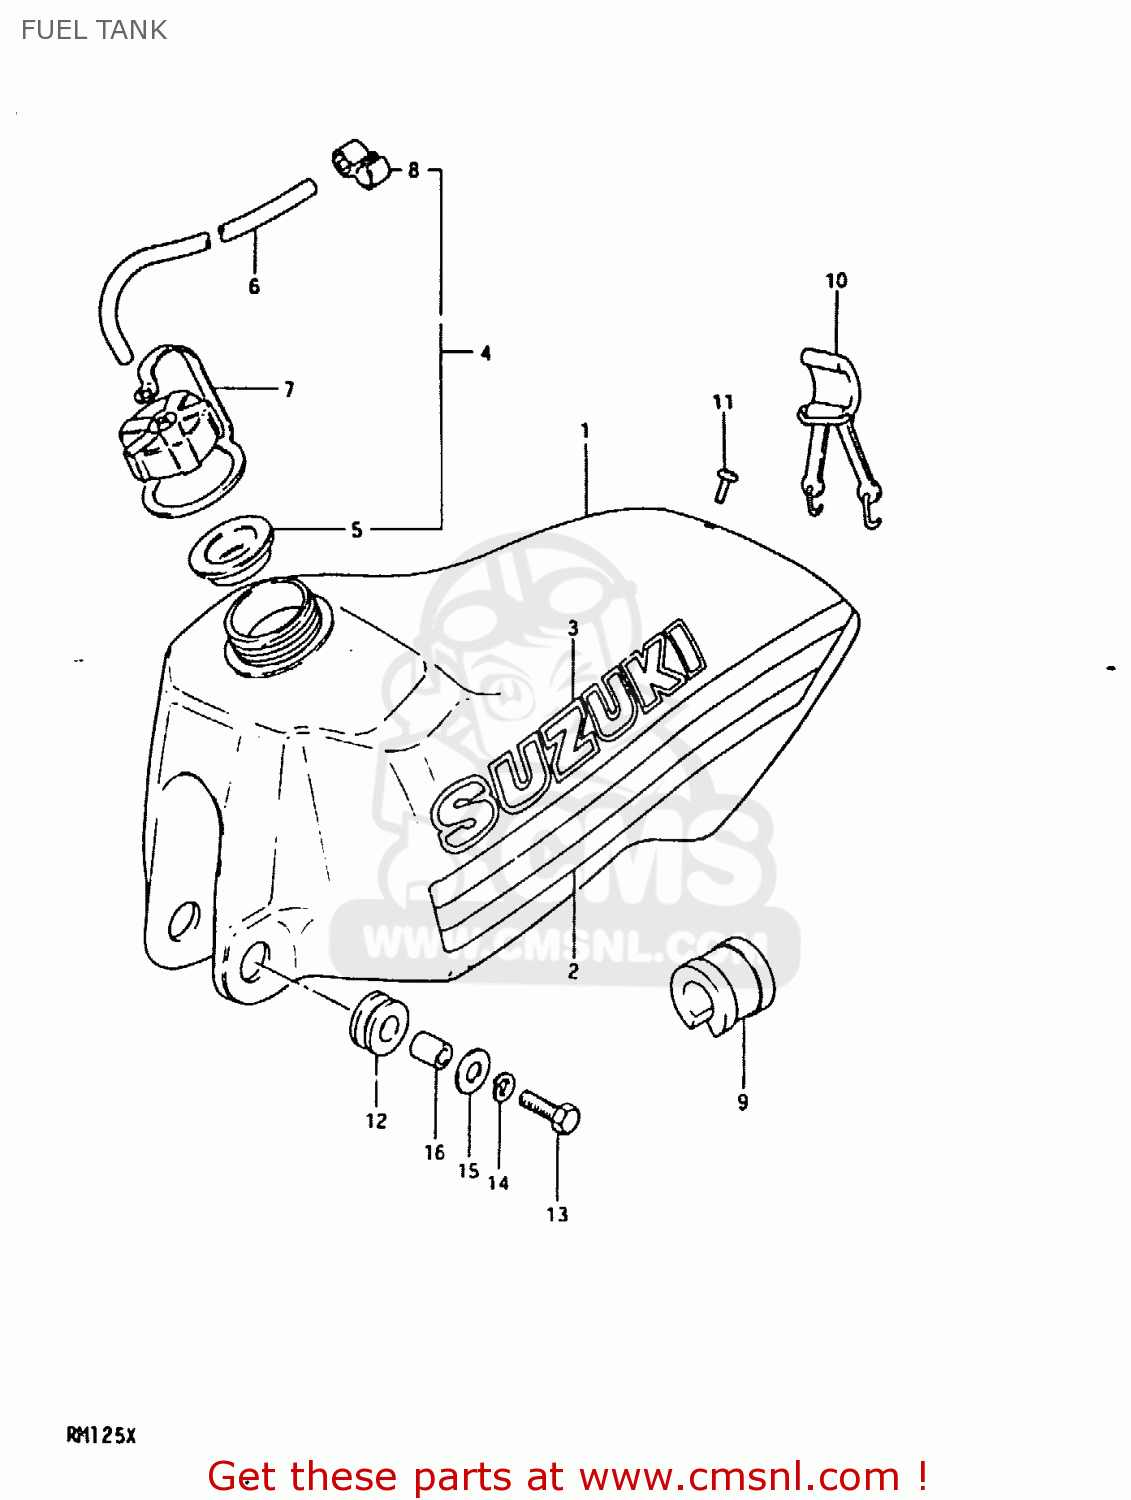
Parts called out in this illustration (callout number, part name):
1	TANK, FUEL (YELLOW)
2	TAPE SET
3	EMBLEM (BLACK)
4	CAP SET,FUEL TANK
5	GASKET,FUEL TANK CAP (NAS)
6	HOSE
7	BAND,FUEL TANK CAP
8	CLAMP,BREATHER HOSE
9	CUSHION,FUEL TANK UPR
10	BAND,FUEL TANK,REAR
11	SCREW (6X15)
12	CUSHION
13	BOLT (8X30)
14	LOCK WASHER
15	WASHER (8.5X29X1.6)
16	SPACER (8.8X12X15.5)
